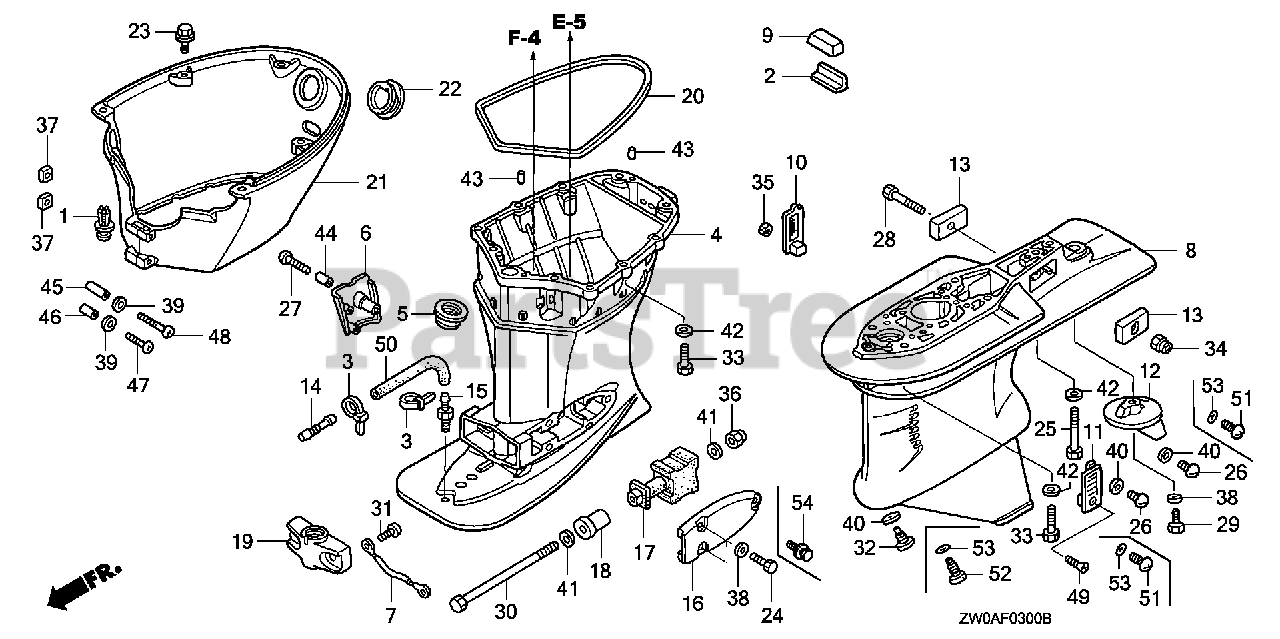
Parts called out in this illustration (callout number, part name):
1	CLIP, FUEL PIPE (BLACK)
2	PLATE, RUBBER SETTING
3	BAND, WIRE
4	CASE, EXTENSION *NH282MU* (L) (OYSTER SILVER METALLIC-U)
5	RUBBER, DRAIN PLUG
6	COVER, DRAIN PLUG *NH282MU* (OYSTER SILVER METALLIC-U)
7	WIRE, LEAD (1.2X116MM)
7	WIRE, LEAD (1.5X116MM)
8	CASE, GEAR *NH282MU* (OYSTER SILVER METALLIC-U) (NA USE ALT:41101-ZW1-B05ZA)
8	CASE, GEAR *NH282MU* (OYSTER SILVER METALLIC-U)
9	GROMMET, GEAR CASE
10	SCREEN, R. WATER
11	SCREEN, L. WATER
12	TAB, TRIM *NH282MU* (OYSTER SILVER METALLIC-U)
13	METAL, ANODE
14	END, NIPPLE
15	NIPPLE, SENSOR
16	HOUSING, MOUNTING (LOWER) *NH282MU* (OYSTER SILVER METALLIC-U)
17	RUBBER, MOUNT (LOWER)
18	COLLAR, MOUNTING (LOWER)
19	HOUSING, CENTER MOUNTING (LOWER) (NH282MU)
20	RUBBER, COVER (LOWER)
21	COVER (LOWER) *NH282MU* (OYSTER SILVER METALLIC-U)
22	GROMMET, COVER (LOWER)
23	BOLT, FLANGE (6X12)
24	BOLT, HEX. (8X30)
26	BOLT, OIL CHECK (8X8)
27	SCREW, SPECIAL (6X35)
28	BOLT, HEX. (6X32)
29	BOLT, HEX. (8X25)
30	BOLT, HEX. (12X225)
31	SCREW, PAN (6X8)
32	BOLT, DRAIN PLUG (8MM)
33	BOLT, HEX. (10X40)
34	NUT, SELF-LOCK (6MM)
35	NUT, SELF-LOCK (5MM)
36	NUT, SELF-LOCK (12MM)
37	NUT, PLATE (5MM)
38	WASHER, PLAIN (8MM)
39	WASHER, PLAIN (5MM)
40	WASHER, NYLON (8MM)
41	WASHER, PLAIN (12MM)
42	WASHER, PLAIN (10MM)
43	PIN, DOWEL (6X10)
44	COLLAR, DISTANCE (6X10.5X25)
45	COLLAR, DISTANCE (5X7X38)
46	COLLAR, DISTANCE (5X7X23)
47	SCREW, PAN (5X30)
48	SCREW, PAN (5X45)
49	SCREW, OVAL (5X45)
50	BULK HOSE, VACUUM (5X3000) (5X200)
51	BOLT, OIL CHECK
52	BOLT, DRAIN PLUG
53	O-RING (6.9X1.45)
